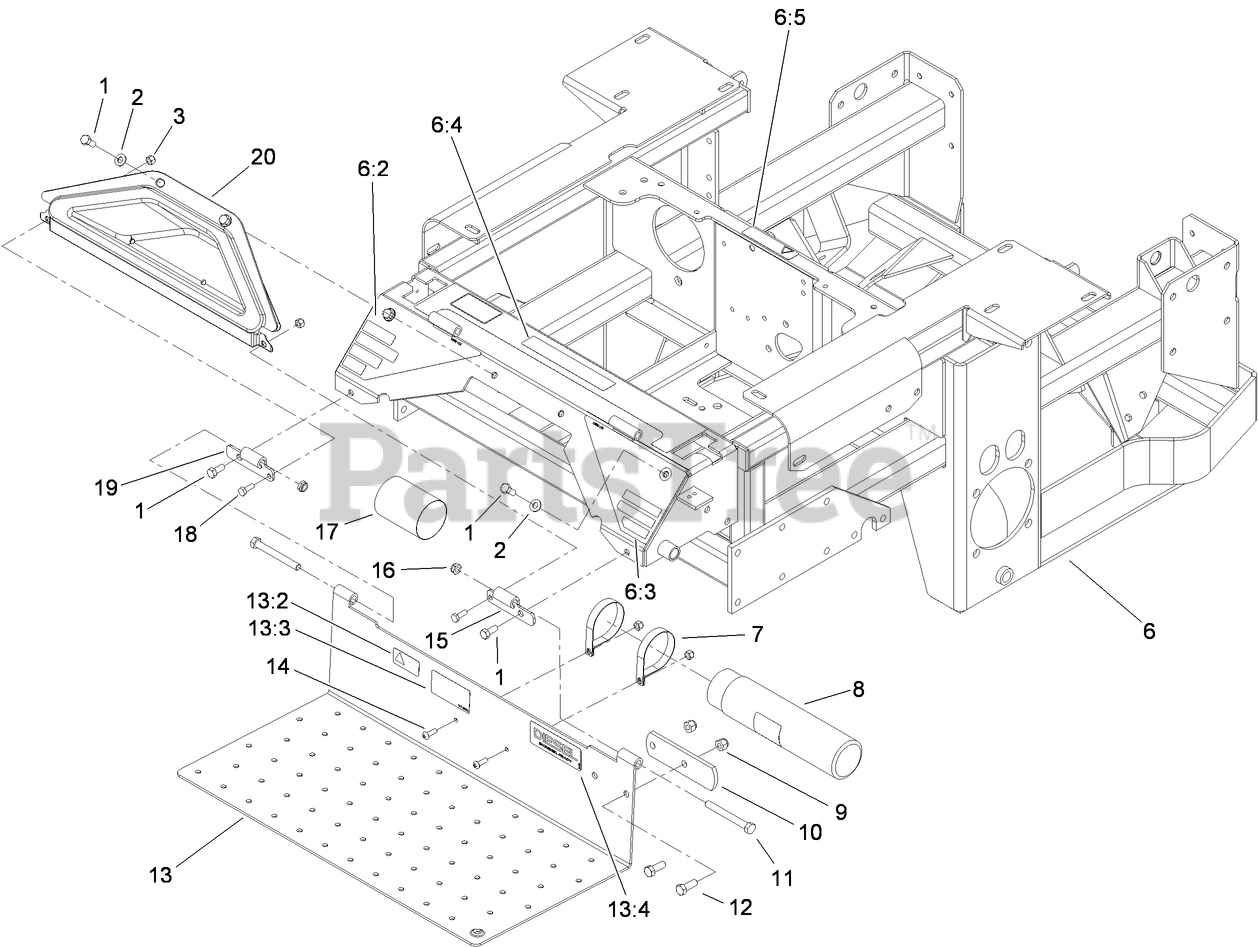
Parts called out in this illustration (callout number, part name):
1	SCREW-HH
2	WASHER-FLAT
3	NUT-LOCK, NI
6	ENGINE FRAME ASM
6:2	Decal-Warning
6:3	Decal-Danger
6:4	DECAL-CONSOLE, TOP
6:5	DECAL-COVER, MISSING
7	R-Clamp
8	TUBE-MANUAL
9	NUT-LOCK, NI
10	STOP-BRAKE, PARK
11	SCREW-HH
12	SCREW-HH
13	FLOOR PAN ASM
13:2	DECAL-PROTECTION, EAR
13:3	Decal-Location, Manual
13:4	DECAL-DIESEL, BIO-READY
14	SCREW-PRH
15	Hinge-Floorpan, LH
16	NUT-LOCK, NI
17	CAP-HOUSING
18	SCREW-HH
19	Hinge-Floorpan, RH
20	Pocket
